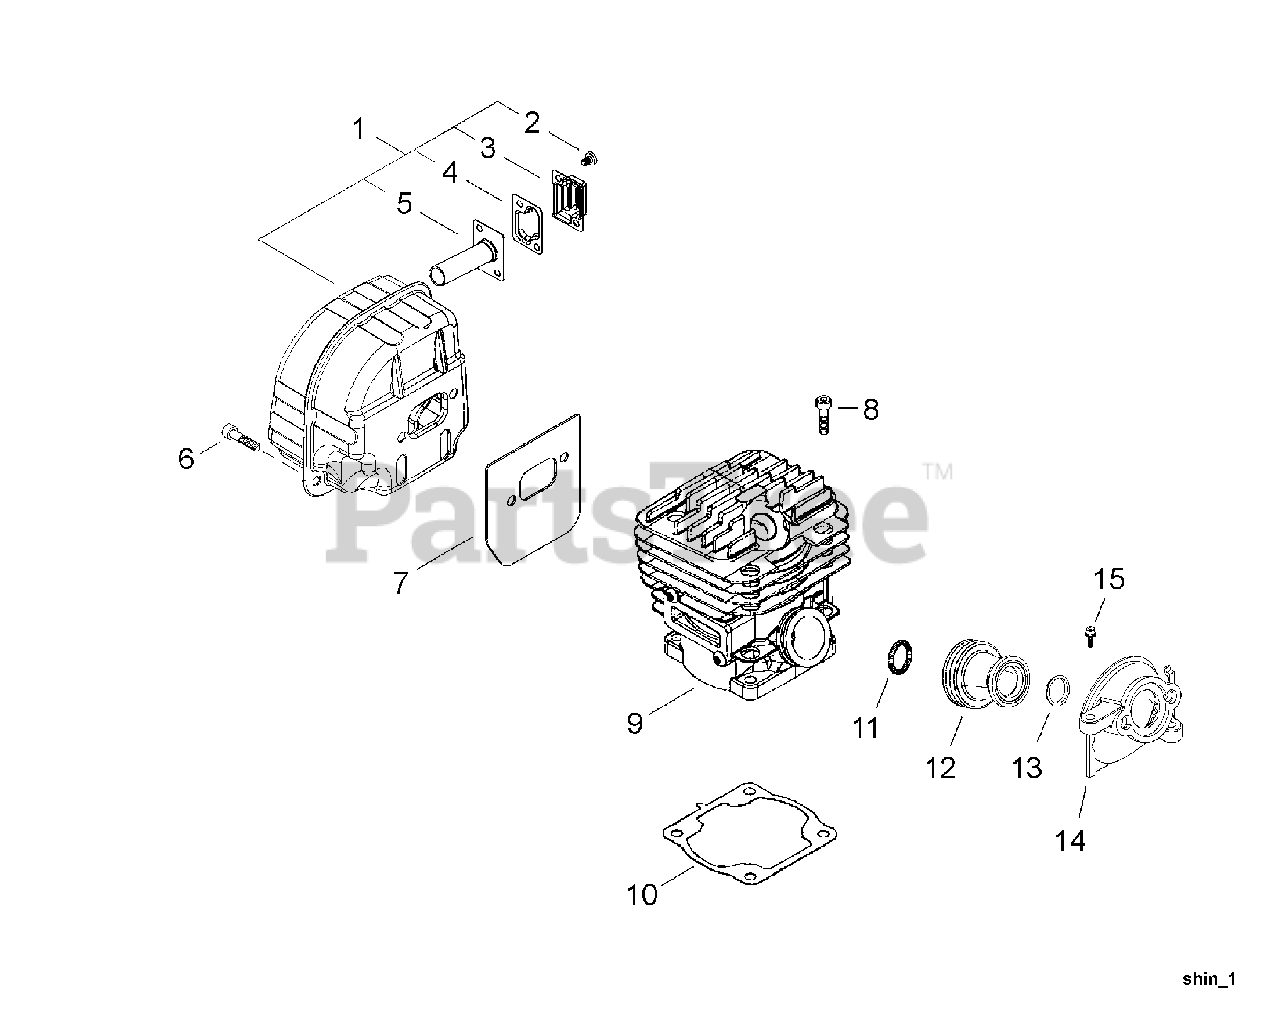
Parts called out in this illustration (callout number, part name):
1	MUFFLER ASSY
2	SCREW - 4X6
3	GUIDE, EXHAUST
4	SCREEN, SPARK ARRESTOR
5	GUIDE, EXHAUST
6	SCREW - 5X18
7	SHIELD, EXHAUST
8	SCREW - 5X18
9	CYLINDER ASSY
10	GASKET, CYLINDER
11	SPRING
12	BOOT, INTAKE
13	SLEEVE
14	BRACKET, INTAKE
15	SCREW - 4X16
